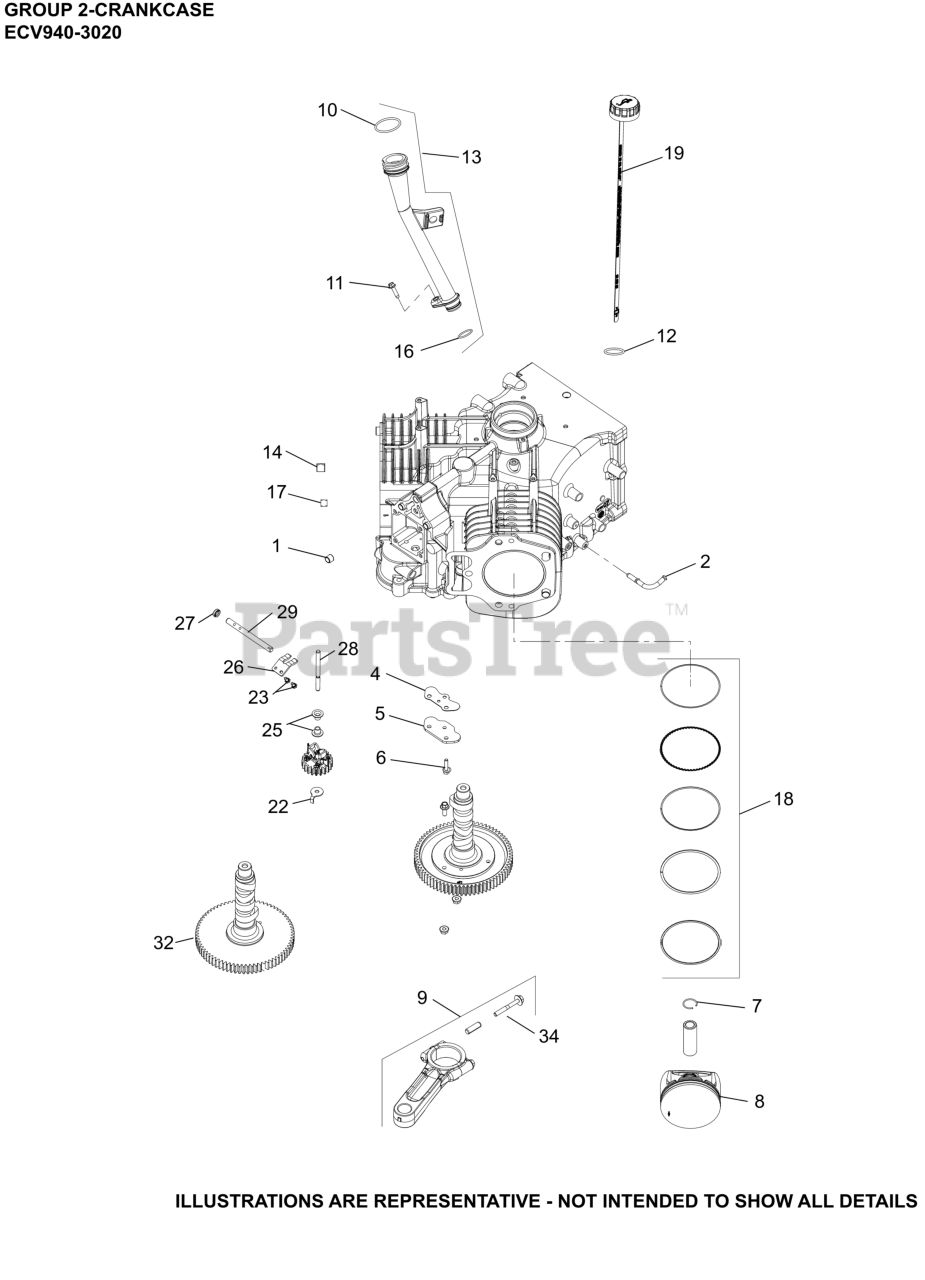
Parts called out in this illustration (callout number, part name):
2	FITTING, PULSE PUMP
4	GASKET, LIFTER FEED COVER
5	KIT, COVER, LIFTER FEED
6	SCREW, HEAVY HEX FLANGE
7	RETAINER, PISTON PIN
8	KIT, PISTON (STD)
8	KIT, PISTON (0.25 OS)
8	KIT, PISTON (0.50 OS)
9	CONNECTING ROD ASSEMBLY
10	O-RING, UPPER OIL FILL TUBE
11	SCREW, THD FRM-USE 25 086 473-S
12	O-RING, DIPSTICK
13	KIT,OIL FILL TUBE
14	PIN, LOCATING
17	PLUG, CTSK PIPE 1/8"
18	RING, SET PISTON (STD) "STYLE B ONLY"
19	DIPSTICK ASSEMBLY
22	TAB, LOCKING
23	SCREW, HEX HEAD
25	PIN, GOVERNOR REGULATING
26	YOKE, GOVERNOR
27	SEAL, GOVERNOR CROSS SHAFT
28	SHAFT, GOVERNOR GEAR
29	SHAFT, GOVERNOR CROSS
32	KIT, CAMSHAFT
34	KIT, ROD BOLTS
NI	SEAL, OIL (RIGHT-HAND HELIX, FWE)
NI	KIT, GOVERNOR GEAR
